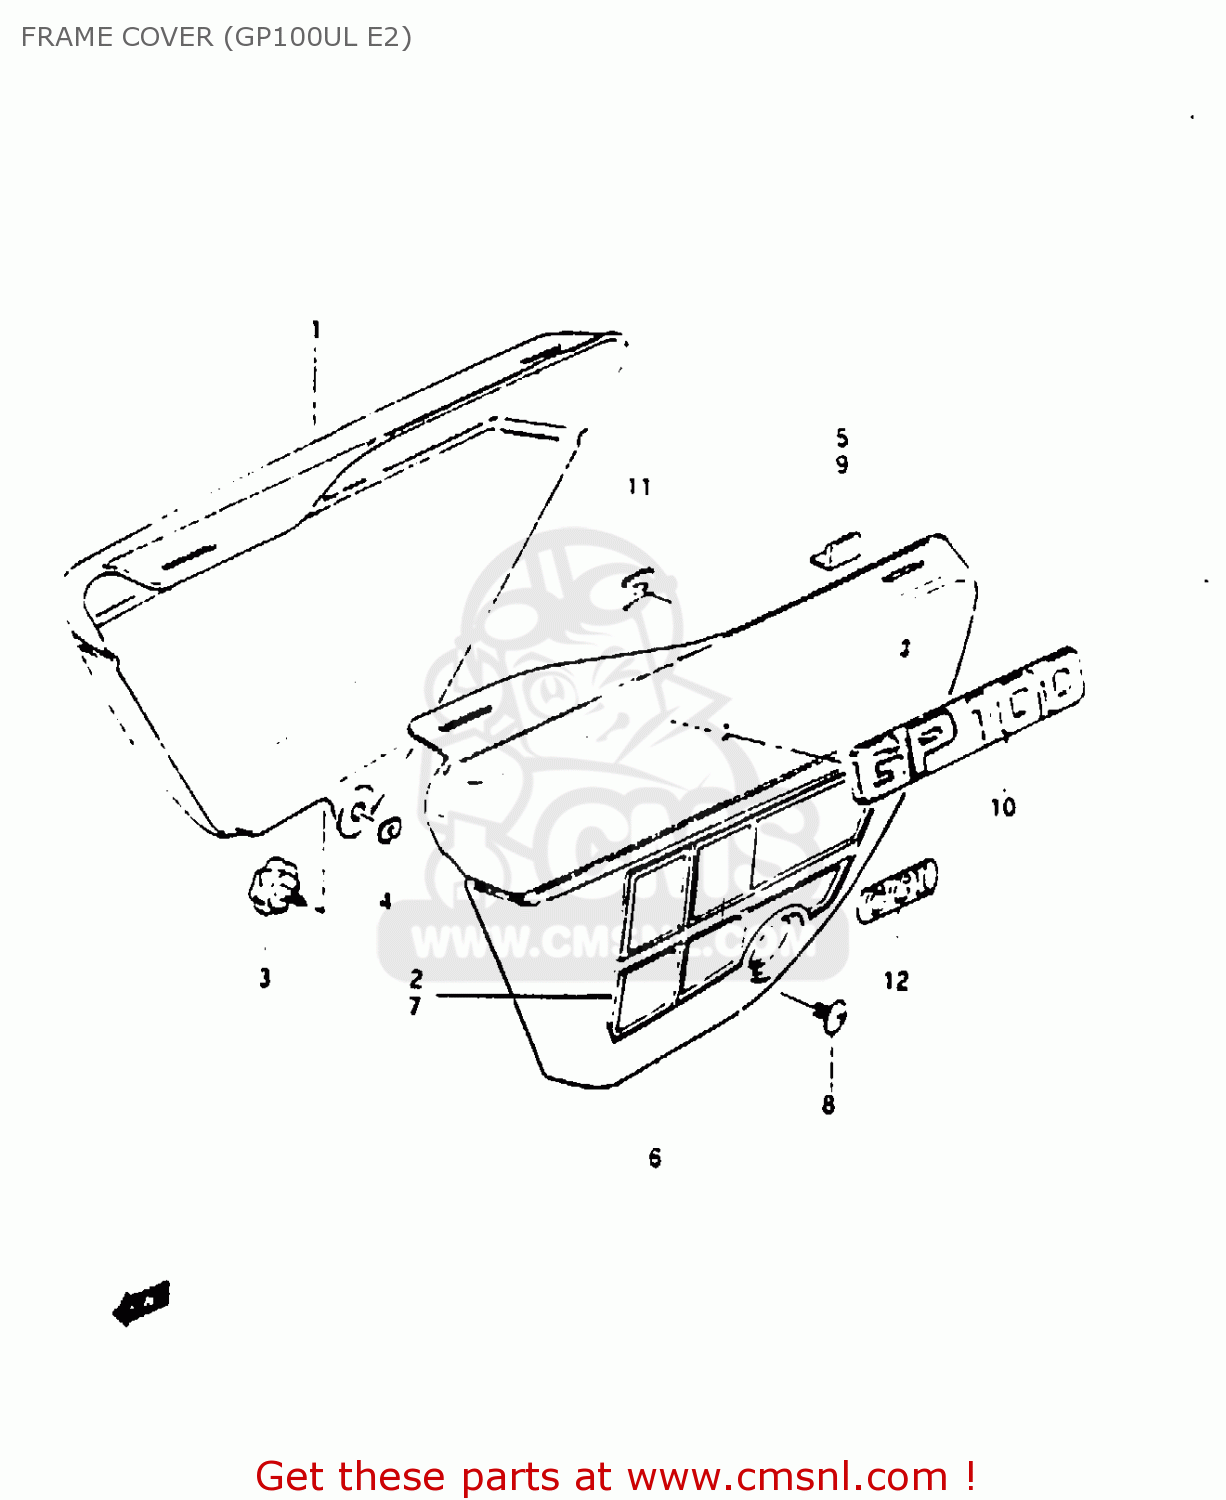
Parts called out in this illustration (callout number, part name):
1	COVER,FRAME,R(BLUE)
2	TAPE SET, FRAME COVER RH
3	KNOB,FRAME COVER,R
4	NUT
5	CUSHION,FRAME COVER
6	COVER, FRAME LH (RED)
7	TAPE SET, FRAME COVER LH
8	SCREW
9	CUSHION,FRAME COVER
10	EMBLEM
11	NUT
12	EMBLEM,CCIS
